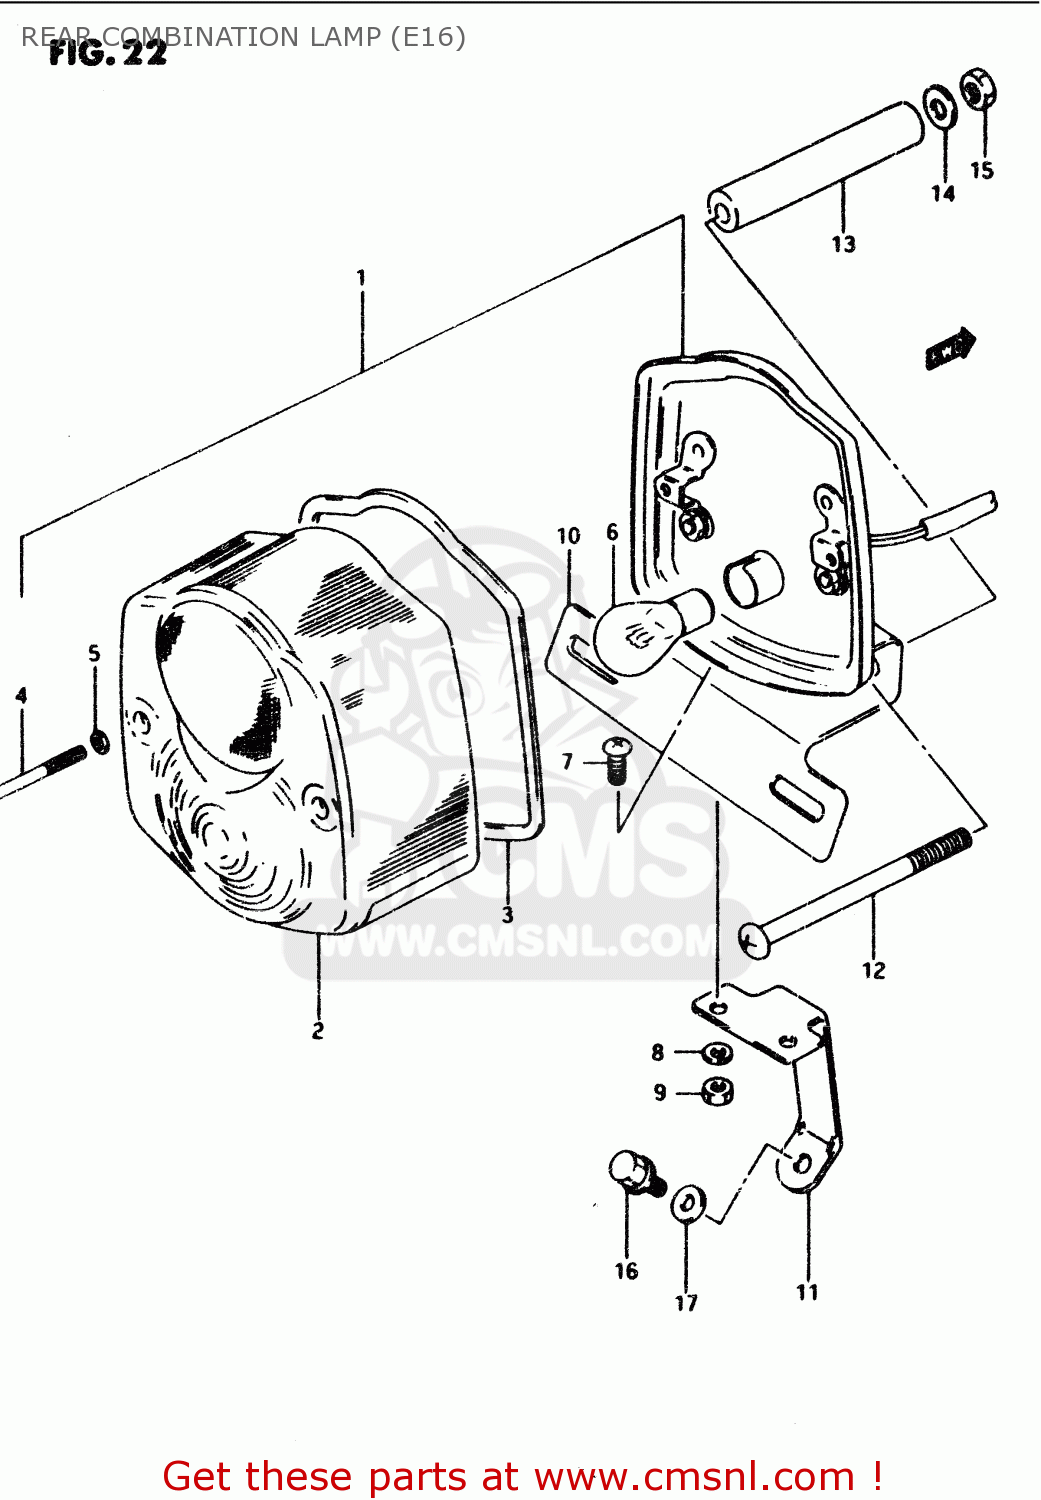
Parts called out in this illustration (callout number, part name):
1	LAMP UNIT, TAIL
2	LENS
3	GASKET (NAS)
4	SCREW
5	GASKET (NAS)
6	BULB (6V,21/5W)
7	SCREW
8	LOCK WASHER
9	NUT
10	PLATE
11	BRACKET
12	SCREW(6X105)
13	SPACER
14	WASHER
15	NUT 6MM
16	BOLT
17	WASHER, LOWER
